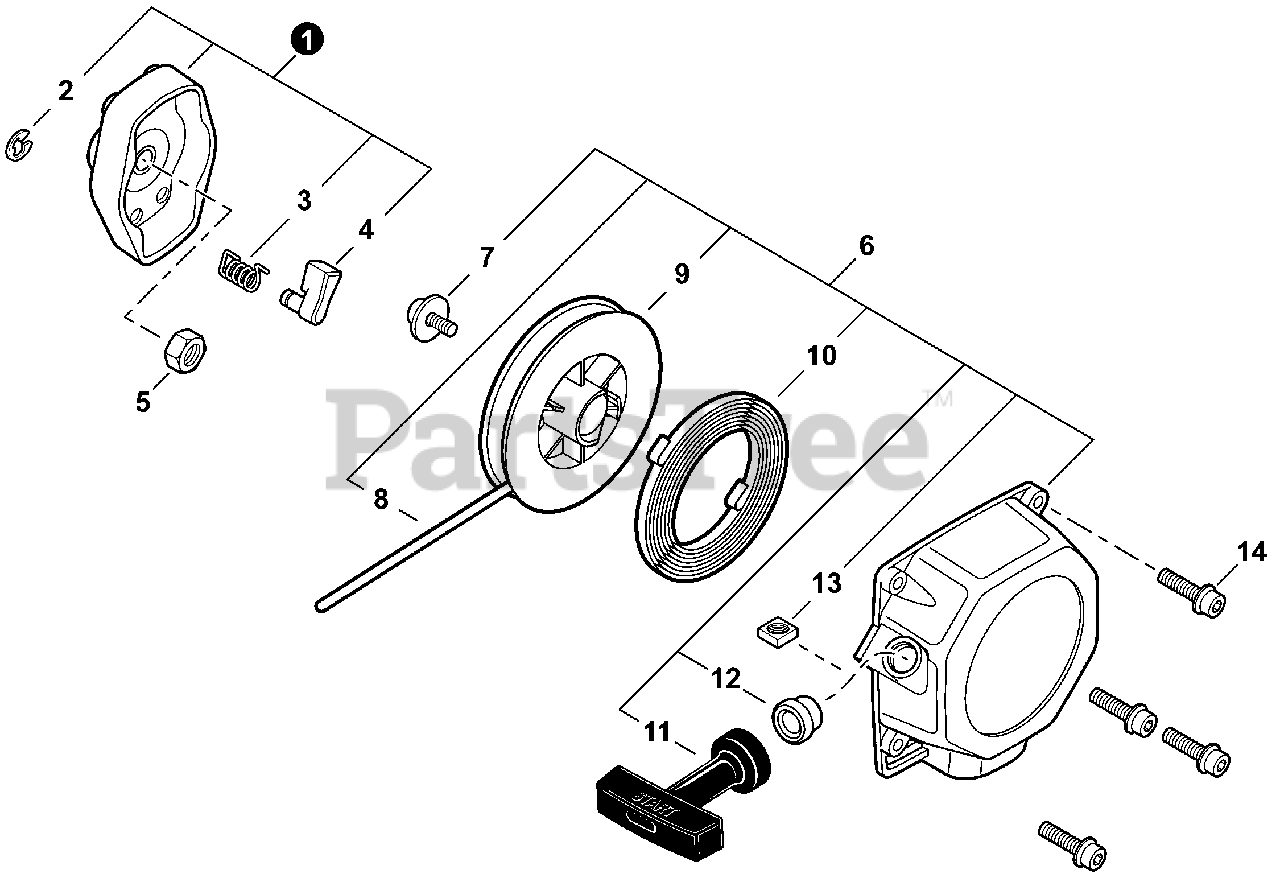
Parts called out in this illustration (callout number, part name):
1	PULLEY ASSY, STARTER
2	E-RING 4
3	SPRING, RETURN
4	PAWL, STARTER
5	NUT 8×1.25
6	STARTER, RECOIL
7	SCREW
8	ROPE, STARTER 3.5×900
9	REEL, ROPE
10	SPRING, RECOIL
11	GRIP, STARTER
12	GUIDE, ROPE
13	NUT M5
14	SCREW 5×16
